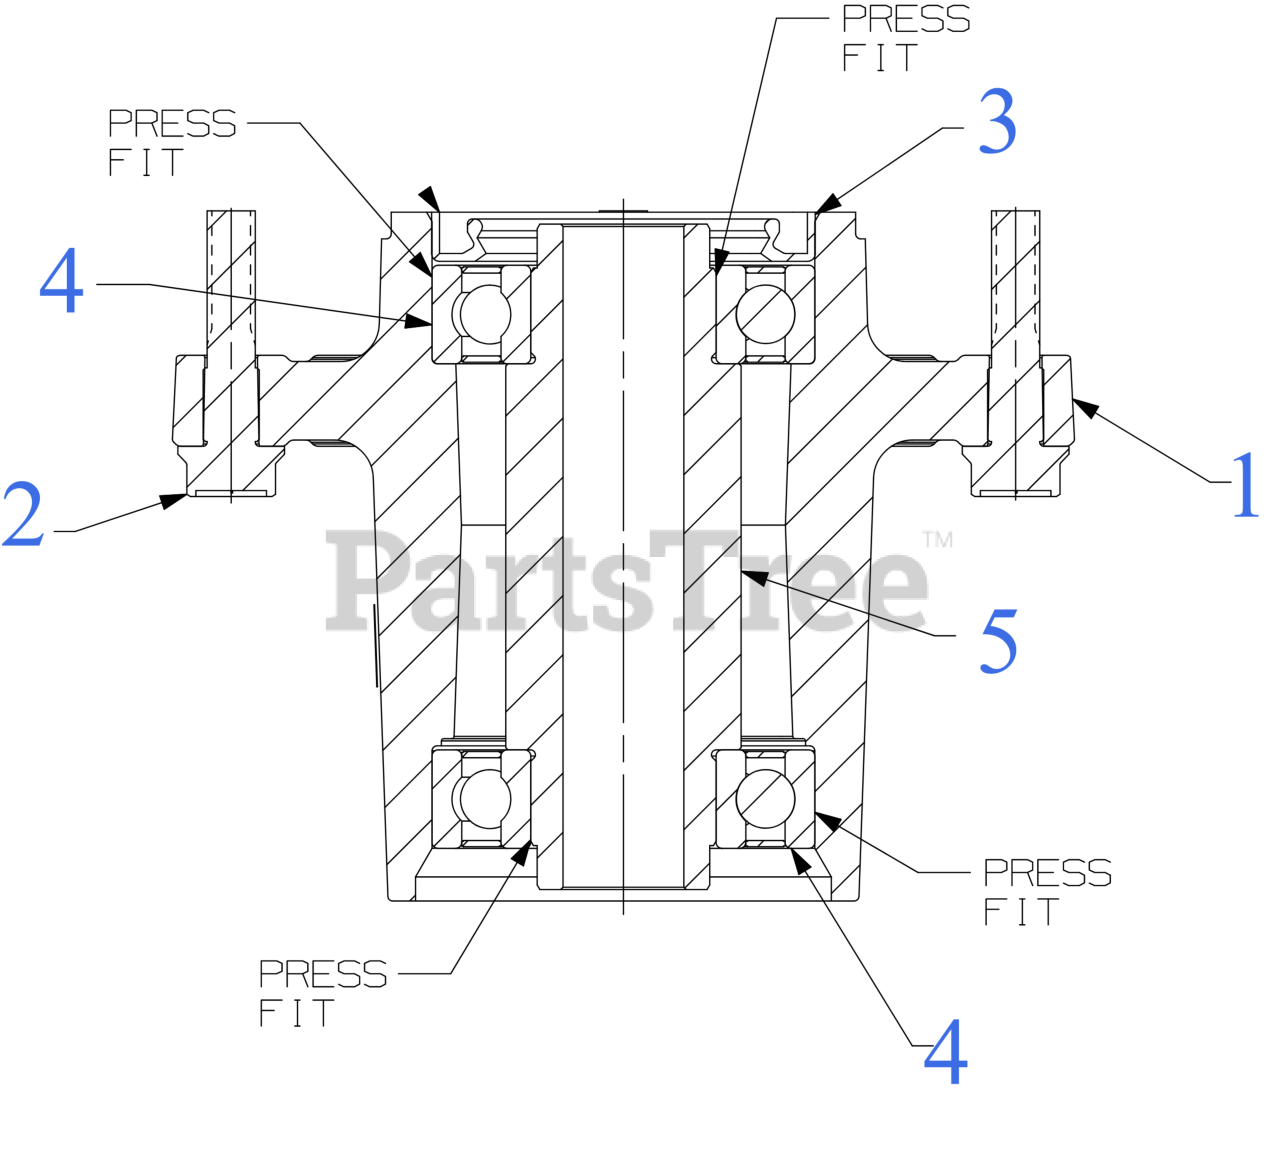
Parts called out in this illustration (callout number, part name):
1	SPINDLE HOUSING
2	BOLT 5/16-18 x 1.50 GR5
3	OIL SEAL
4	SEALED BALL BEARING (30 x 62 x 16)
5	SPACER (.760 x 1.50 x 2.461)
